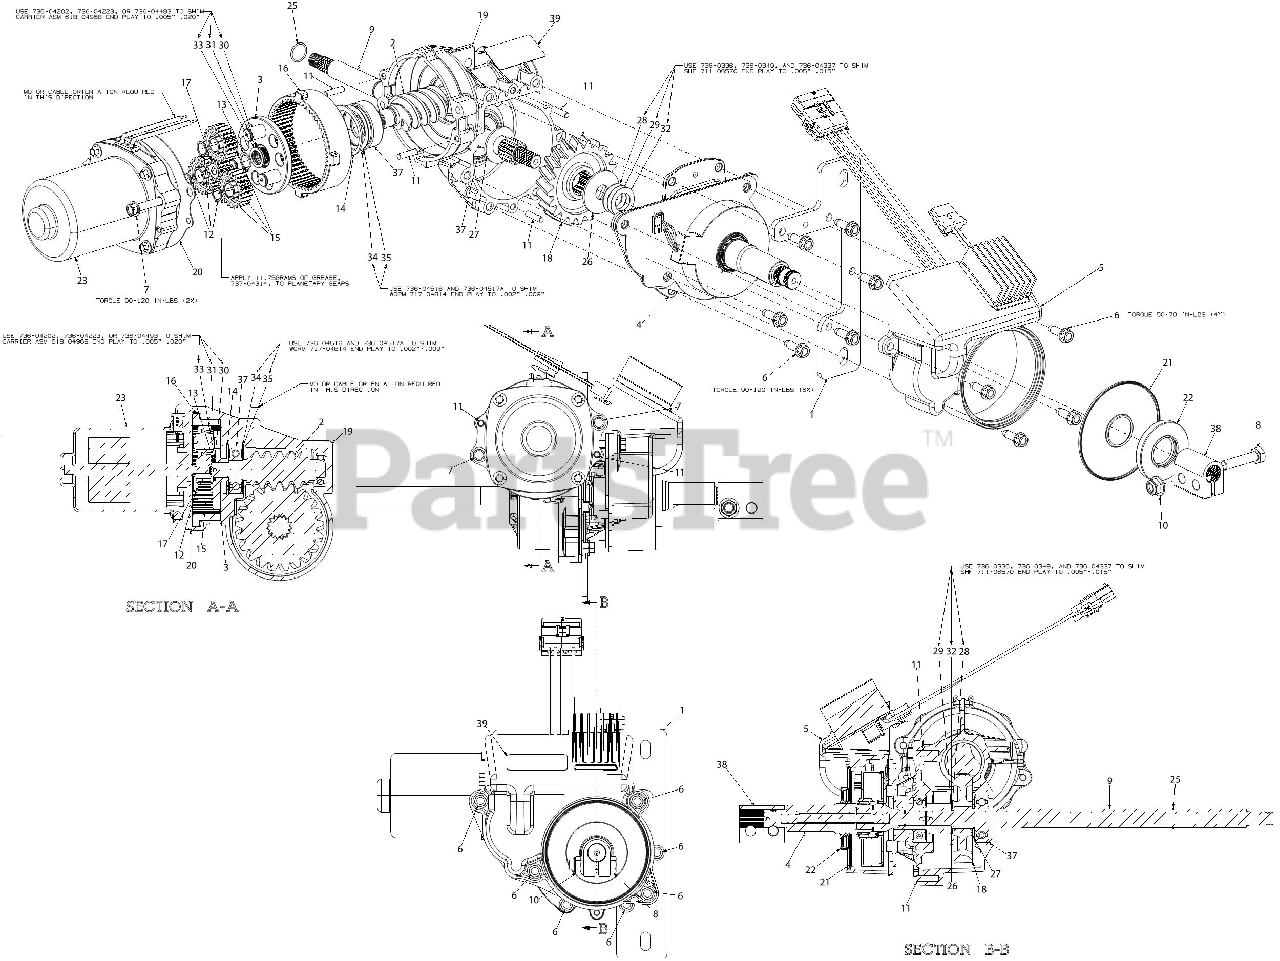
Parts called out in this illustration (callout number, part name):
1	BRACKET ASSEMBLY
2	SHAFT ASSEMBLY
3	CARRIER ASSEMBLY
4	TORSION ASSEMBLY
6	SCREW 1/4-20 x .750
7	SCREW 1/4-20 x 1.25
8	BOLT 5/16-18X1.375 GR5
9	DRIVE SHAFT
10	FLANGE LOCK NUT 5/16-18
11	DOWEL PIN
12	SNAP RING
13	RETAINING RING .500
14	INTERNAL SNAP RING
15	23T PLANET GEAR
16	60T RING GEAR
17	12T SUN GEAR
18	21T HELICAL GEAR
19	MAIN HOUSING
20	EPS MOTOR GASKET
21	OIL SEAL
22	OIL SEAL 1.0X2.04X.27
23	ELECTRIC MOTOR
25	WIRE RING
26	WASHER .51 x 1.5 x .07
27	FLAT WASHER
28	FLAT WASHER
29	FLAT WASHER
30	FLAT WASHER .504 X.700X.010
31	SHIM WASHER
32	SHIM WASHER .632X1.000X.010:HD
33	SHIM WASHER .504X.700X.020
34	SHIM WASHER
35	SHIM WASHER
37	BALL BEARING
38	STEERING SHAFT COUPLER
39	LABEL
